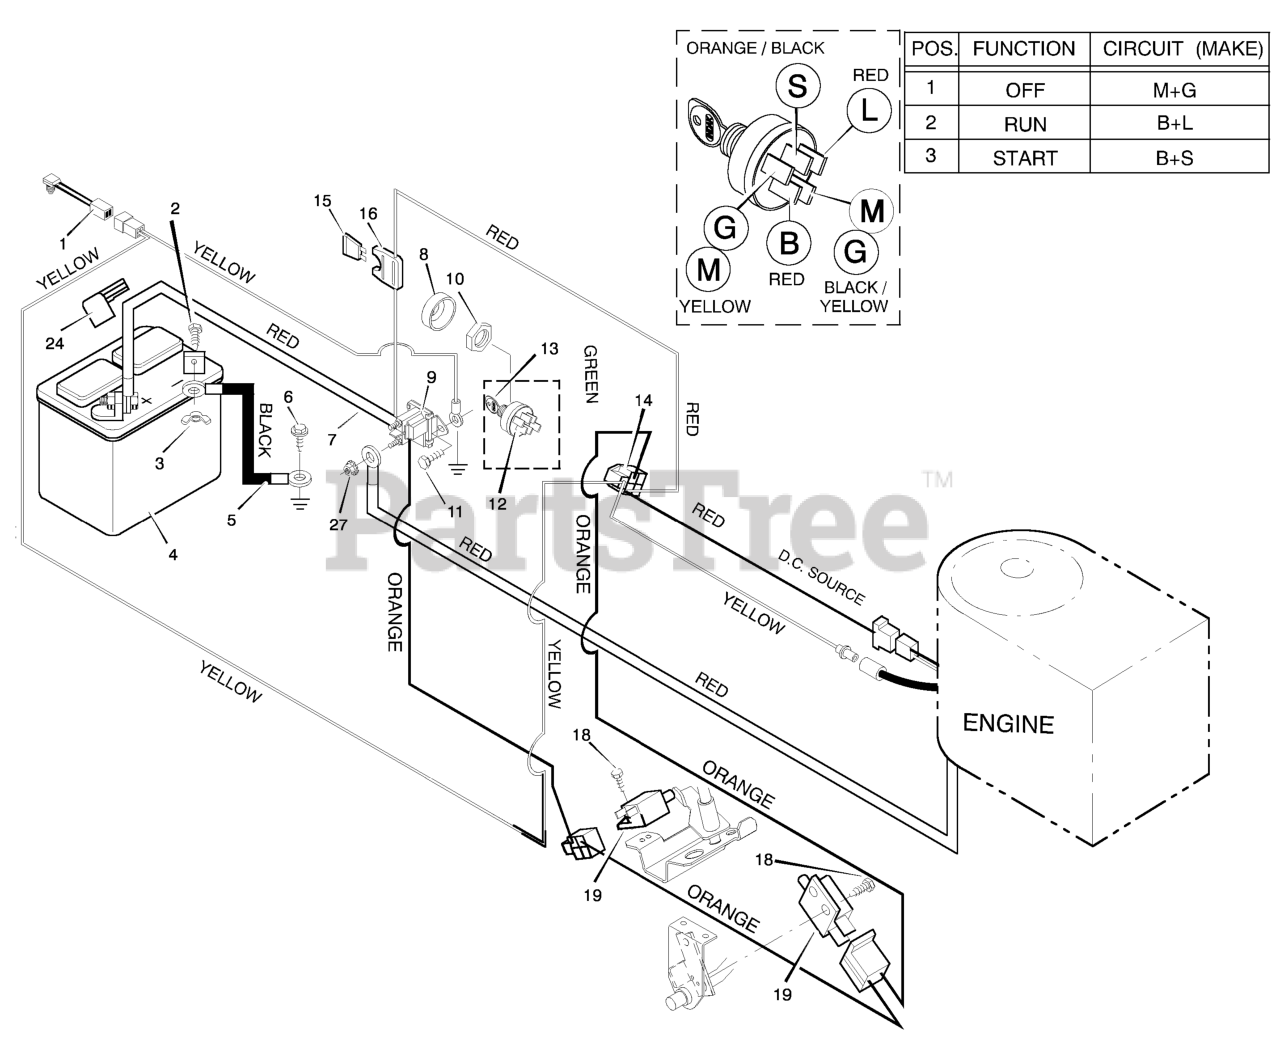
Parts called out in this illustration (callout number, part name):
1	Switch, Seat Sensor
2	Bolt
3	Wingnut
4	Battery
5	Cable, Battery Ground
7	Cable, Red Battery
8	Cap, Ignition
9	Solenoid
10	Nut
12	Switch, Ignition
13	Key, Ignition
14	Harness, Chassis Wire
16	Holder, Fuse
19	Switch, Clutch
24	Cover, Terminal
27	Locknut
